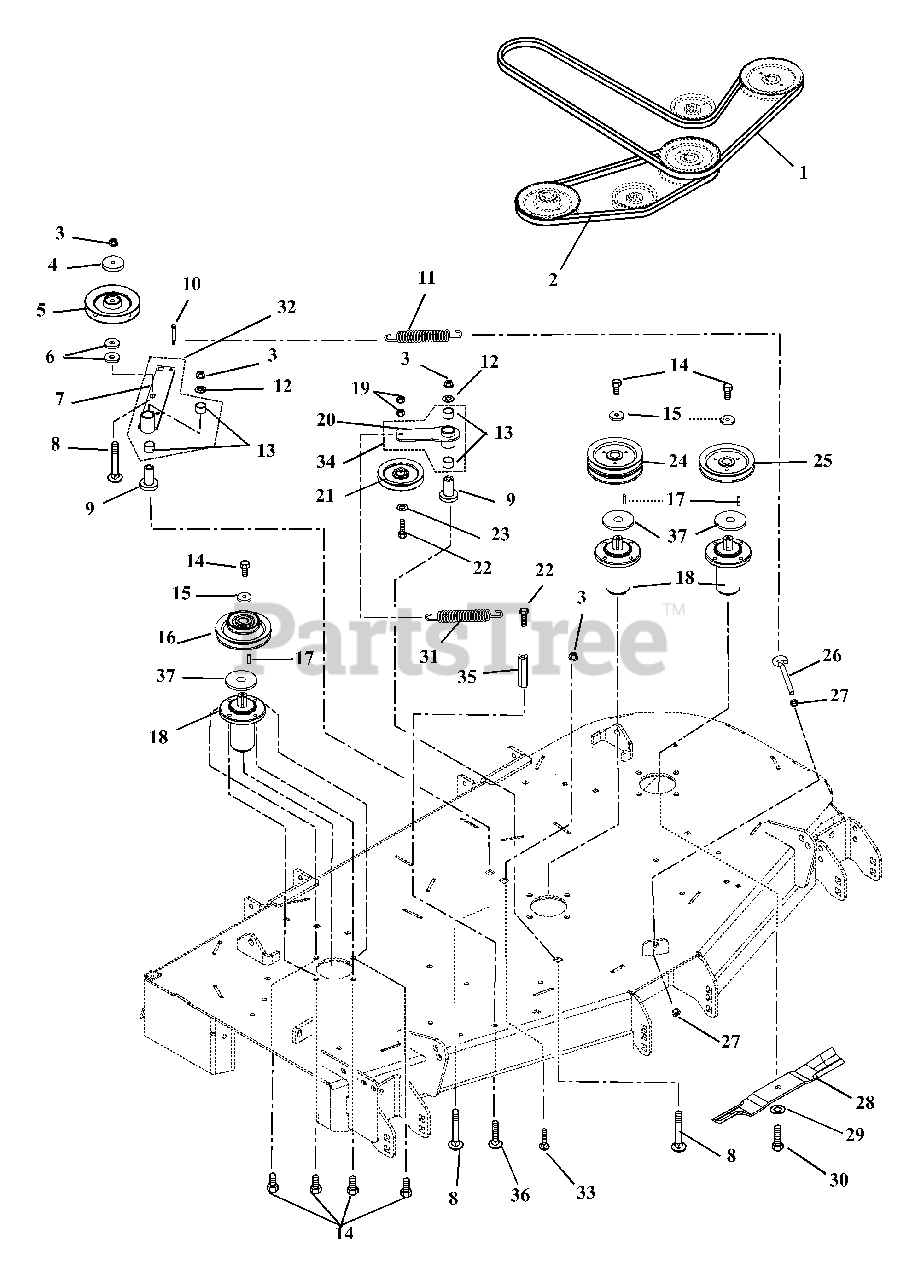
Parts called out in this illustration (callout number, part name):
1	Belt, 175" Long, PTO Drive Hex
1	Belt, 184.4" Long, PTO Drive Hex
1	Belt, 199" Long, PTO Drive Hex
2	V-Belt, 56" Long Cog B-Section
2	V-Belt, 63" Long Cog B-Section
2	V-Belt, 76" Long Cog B-Section
3	Nut, .50-13 Nyloc Flange
4	Cap, Idler Bearing Sealing
5	Pulley, V 6.0 x .500 ID DBL. Bearing
6	Washer, Flat Steel .515 x 1.625 x .250
7	Idler, Pivot Arm
8	Bolt, Round Head Square Neck .50-13 x 3.50
9	Bearing, Pedestal
10	Bolt, Shoulder EP .38-16 x .30 Hex
11	Spring, Extension (Deck Idler)
12	Washer, Flat Steel .531 x 1.250 x.100
13	Bearing, 1.00 x 1.12 x .75
14	Bolt, Hex .38-16 x 1.00
15	Washer, Flat Steel .406 x 1.50 x .245
16	Sheave, Double, 1" ID x 6" OD and 3.50" OD
16	Sheave, Double, 1" ID x 6.75" x 4.35" OD
16	Sheave, Double, 1" ID x 8.25" and 5.25" OD
17	Key, Square .25 x .25 x 1 RC 40-50
18	Spindle Assembly
19	Nut, Locking-Center .38-16
20	Idler, Pivot Arm
21	Sheave, .38" ID x 5" OD
22	Bolt, Hex .38-16 x 2.25
23	Washer, Flat Steel .406 x .812 x .065
24	Sheave, Double 1" ID x 6.00" OD
24	Sheave, Double 1" ID x 6.75" OD
24	Sheave, Double 1" ID x 8.25" OD
25	Sheave, Single 1" ID x 6.00" OD
25	Sheave, Single 1" ID x 6.75" OD
25	Sheave, Single 1"ID x 8.25" OD
26	Bolt, .38-16 x 4.50 .62 Diameter Eye
27	Nut, Hex, Jam .375-16
28	Blade, 18.00" Mower (HI-LIFT)
28	Blade, Mower (20.50")
28	Blade, Mower (24.50") without Tungsten Carbide Hardfacing
29	Washer, Bellville .63 x 1.625 x.14
30	Bolt, Hex .62-18 x 1.75 Grade 8
31	Spring, Extension
32	Assembly, PTO Idler Pivot Arm
33	Bolt, Round Head Square Neck .50-13 x 1.5, Full Thread, Grade 5
34	Assembly, Idler Pivot Arm
35	Nut, Coupling .375-16 x 1.75
36	Bolt, Round Head Square Neck .38-16 x 1.00
37	Slinger, Dust
